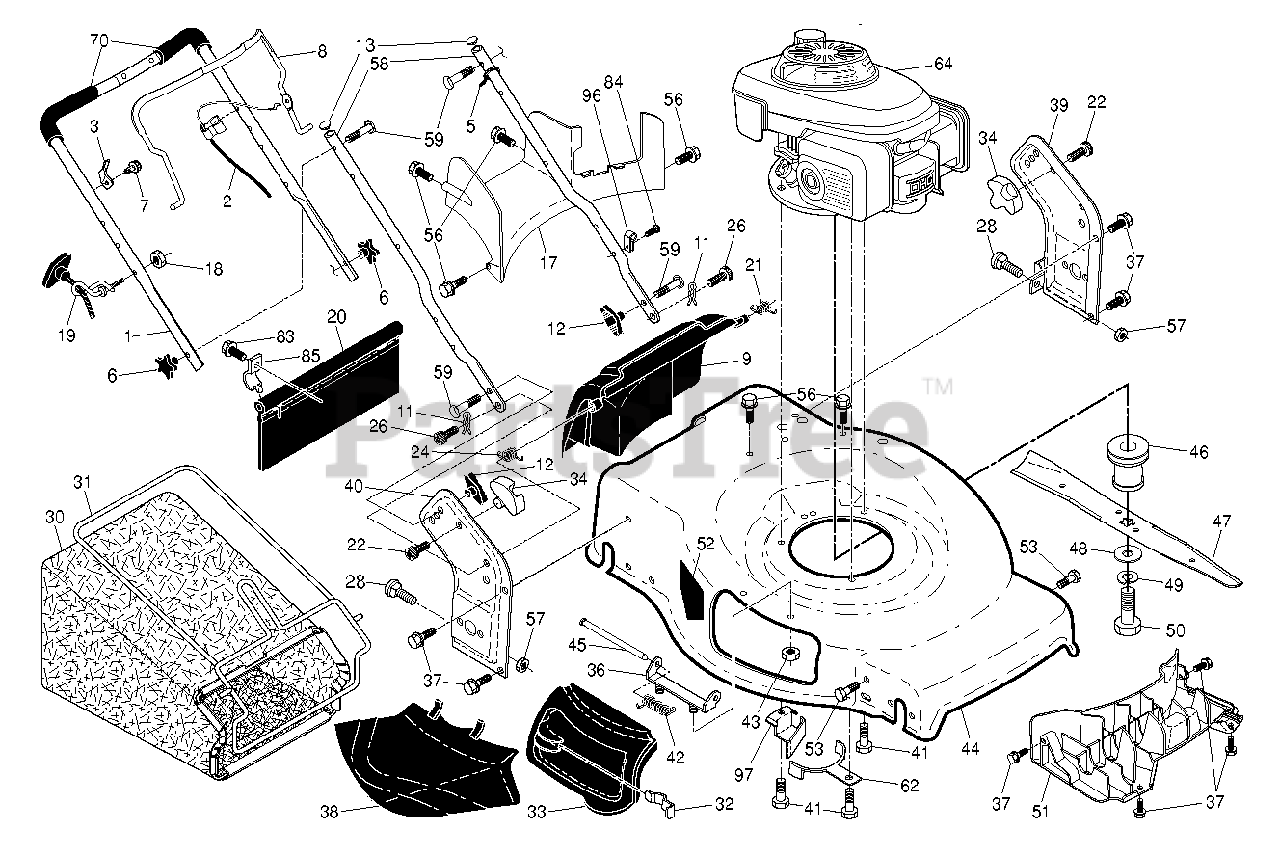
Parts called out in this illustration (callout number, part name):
11	COTTER.HAIRPIN.DOOR/HANDLE.PIV
13	PLUG.PLASTIC.7/8".14-20.GAUGE
17	BAFFLE.REAR.22+.RGD.PL
20	SKIRT.REAR.22+RGD.HIGH WHEEL
21	SPRING.LH.GRAY
24	SPRING.RH.GRAY
26	SCREW,DOOR/HANDLE.PIVOT
31	FRAME.GBAG.22PLUS
32	LATCH.DOOR.ZINC
33	DOOR.MULCH.22 PLUS.HUSQ.GREY
34	BRACKET.GRASSBAG.ATTACHING.BLK
38	DEFLECTOR.CLIPPING.22.BLACK
56	SCREW.HX.13X.750
58	HANDLE.LOWER.22+BT.2PC.GRY
84	FASTENER.PUSH.O.250X0.783
85	BRACKET.SKIRT.22+.BZP
